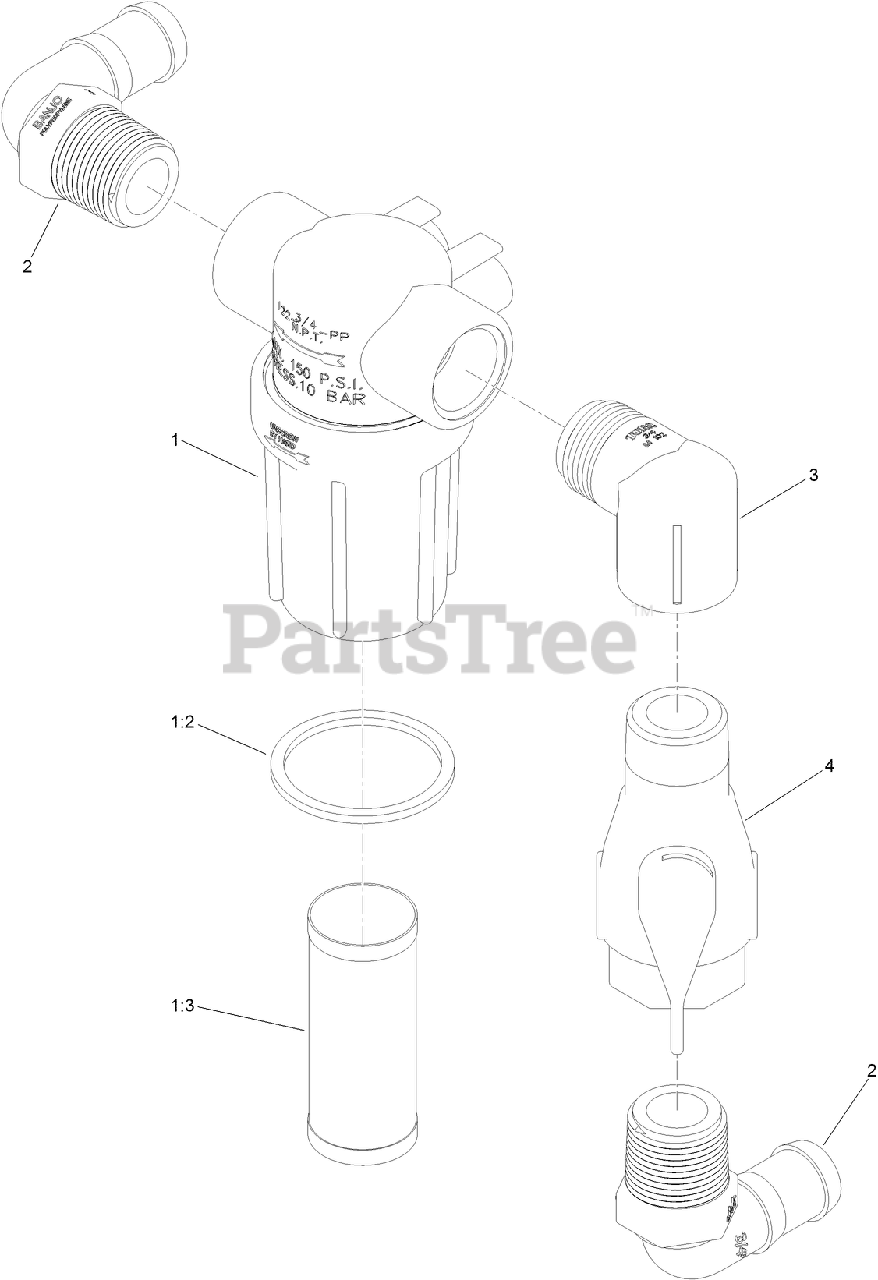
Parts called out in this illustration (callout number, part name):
1	STRAINER-LINE
1:2	GASKET-HEAD, LINE STRAINER
1:3	SCREEN-STRAINER, 30 MESH SS
2	ELBOW-HOSEBARB
4	VALVE-BALL
